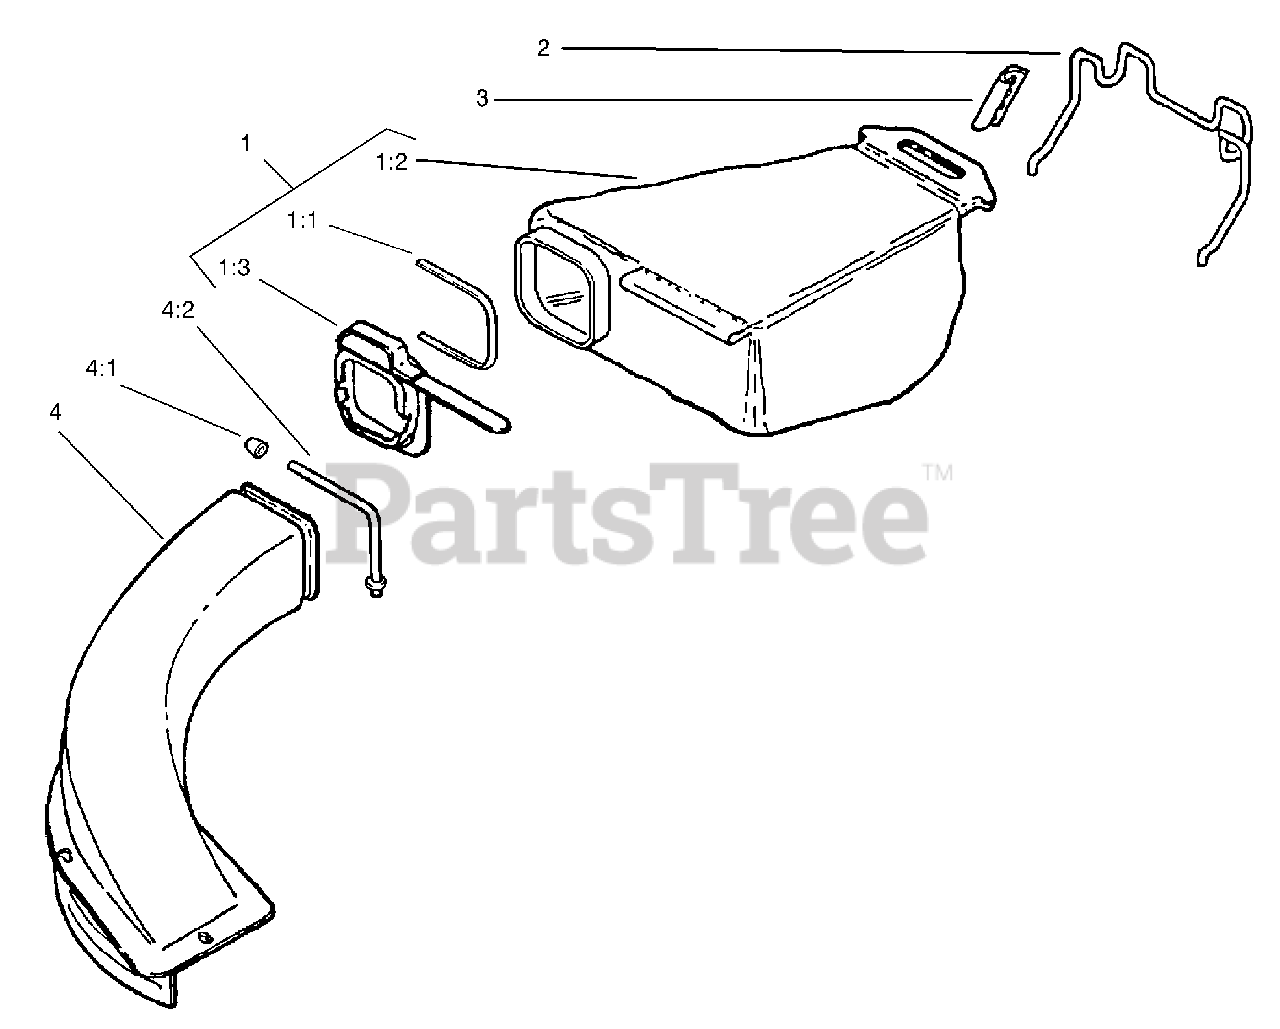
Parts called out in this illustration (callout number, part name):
1	Bag & Adapter ASM. (only on: 10324, 10324c)
1:1	Strap-Tie (only on: 10324, 10324c)
1:2	Replacement Bag ASM. (only on: 10324, 10324c)
1:3	Adapter (only on: 10324, 10324c)
2	Hanger-Wire (only on: 10324, 10324c)
3	Clamp-Hanger (only on: 10324, 10324c)
4	Chute & Support ASM (only on: 10324, 10324c)
4:1	Nut-Cap (only on: 10324, 10324c)
4:2	Support-Chute (only on: 10324, 10324c)
